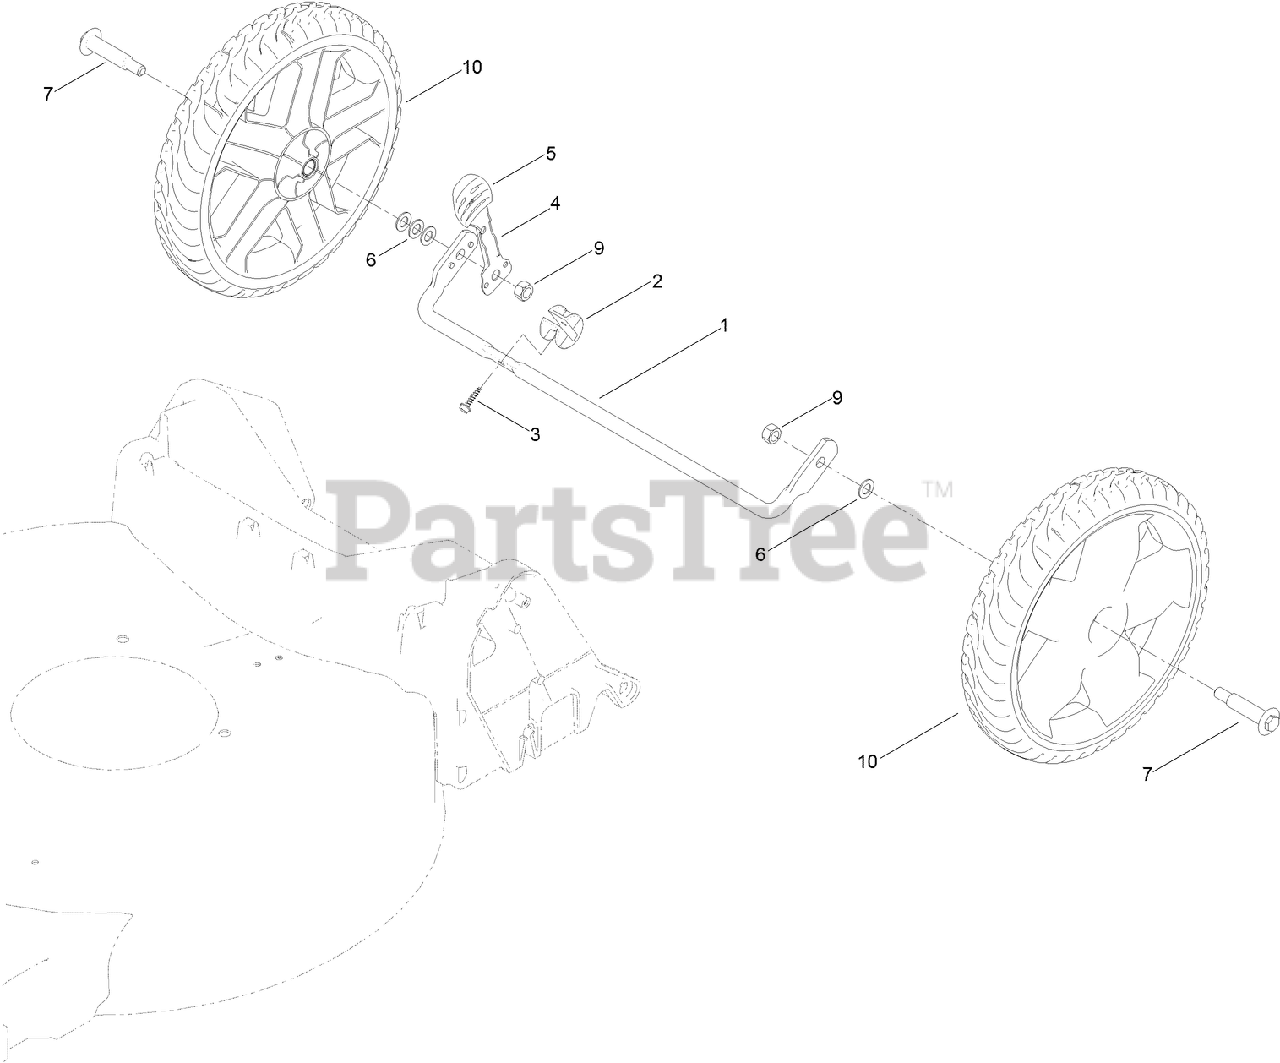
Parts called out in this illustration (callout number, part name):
1	AXLE-REAR
2	STOP-AXLE
3	SCREW-HWH
4	ARM-SPRING, REAR
5	Knob-Lever, HOC
6	WASHER
7	BOLT-SHOULDER
9	NUT-HEX
10	11 INCH WHEEL ASM
